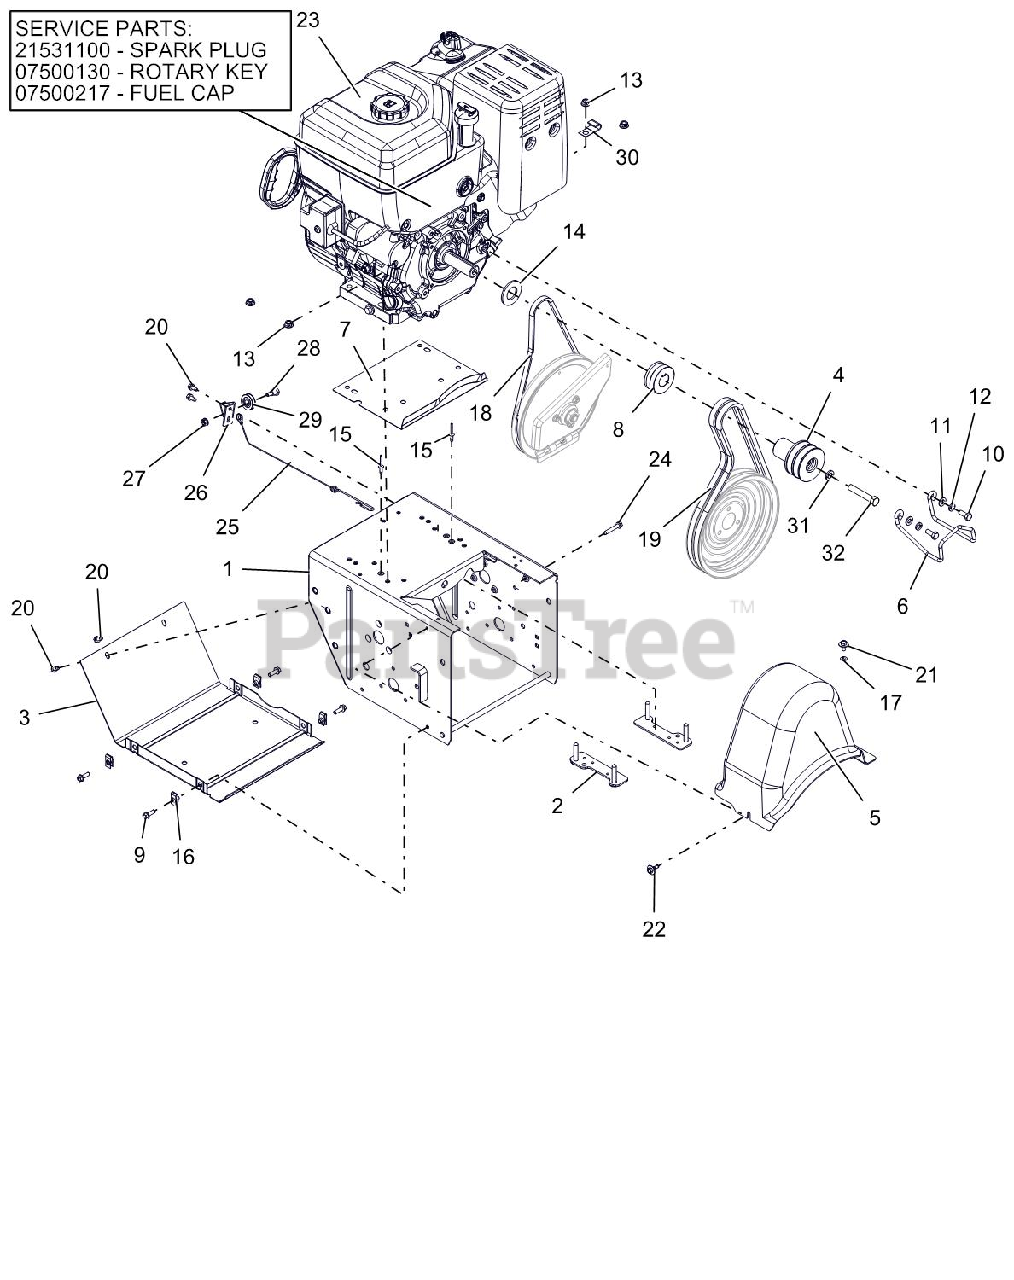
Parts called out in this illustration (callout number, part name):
1	FRAME, MAIN - PRO (WELDMENT)
2	STRAP, BOLT-LARGE
3	COVER, BOTTOM
4	SHEAVE, ATTACHMENT 2-GRV
5	COVER, BELT-LARGE
6	FINGER, BELT
7	BAFFLE, WATER - LARGE BLOCK
8	SHEAVE, DRIVE
9	BLT-HEX .25-20X.75 HWH YZ GR5
10	BLT-HEX .31-24X.75 YWZC GR5
11	@WSHR-FL-STL.344X.688X.065YWZC
12	WSHR-LK .312X.097 HVY YWZC
13	@NUT-LK-CTR-FLG .31-18 YZ GR F
14	WSHR-FL-STL- 1.062X2.0X.134 YZ
15	RVT-POP .187 YZ
16	NUT-RTNR .25-20X.56
17	NUT-PUSH .25X.50 O.D.
18	V-BELT, 3L-WRAPPED
19	V-BELT, HA-RAW EDGE (SET)
20	SCR-TAP .25-20X.50 HWH TR YWZ
21	SCR-TAP .25-20X.50 LGHWH TR YZ
22	SCR-TAP .25-20X.5 CAPTIVE
23	PLUG, SPARK 20HP B&S VANGUARD
23	KEY, IGNITION ROTARY B&S
23	CAP, FUEL - BRIGGS & STRATTON
23	ENGINE, BRIGGS PF 2100, 240V
24	@SCR-TAP .25-20X1.50 HWH TR YZ
25	CABLE, LOWER TRACTION,SS & PRO
26	BRACKET, CABLE PULLEY
27	@NUT-LK-TOP-FLG .25-20 YWZC
28	BOLT, SHLDR-.375X.375X.25-20
29	PULLEY, CABLE
30	J-CLAMP
31	@WSHR-LK .44X.109 REG YWZC
32	BLT-HEX .44-20X2.50 GR5 YWZC
